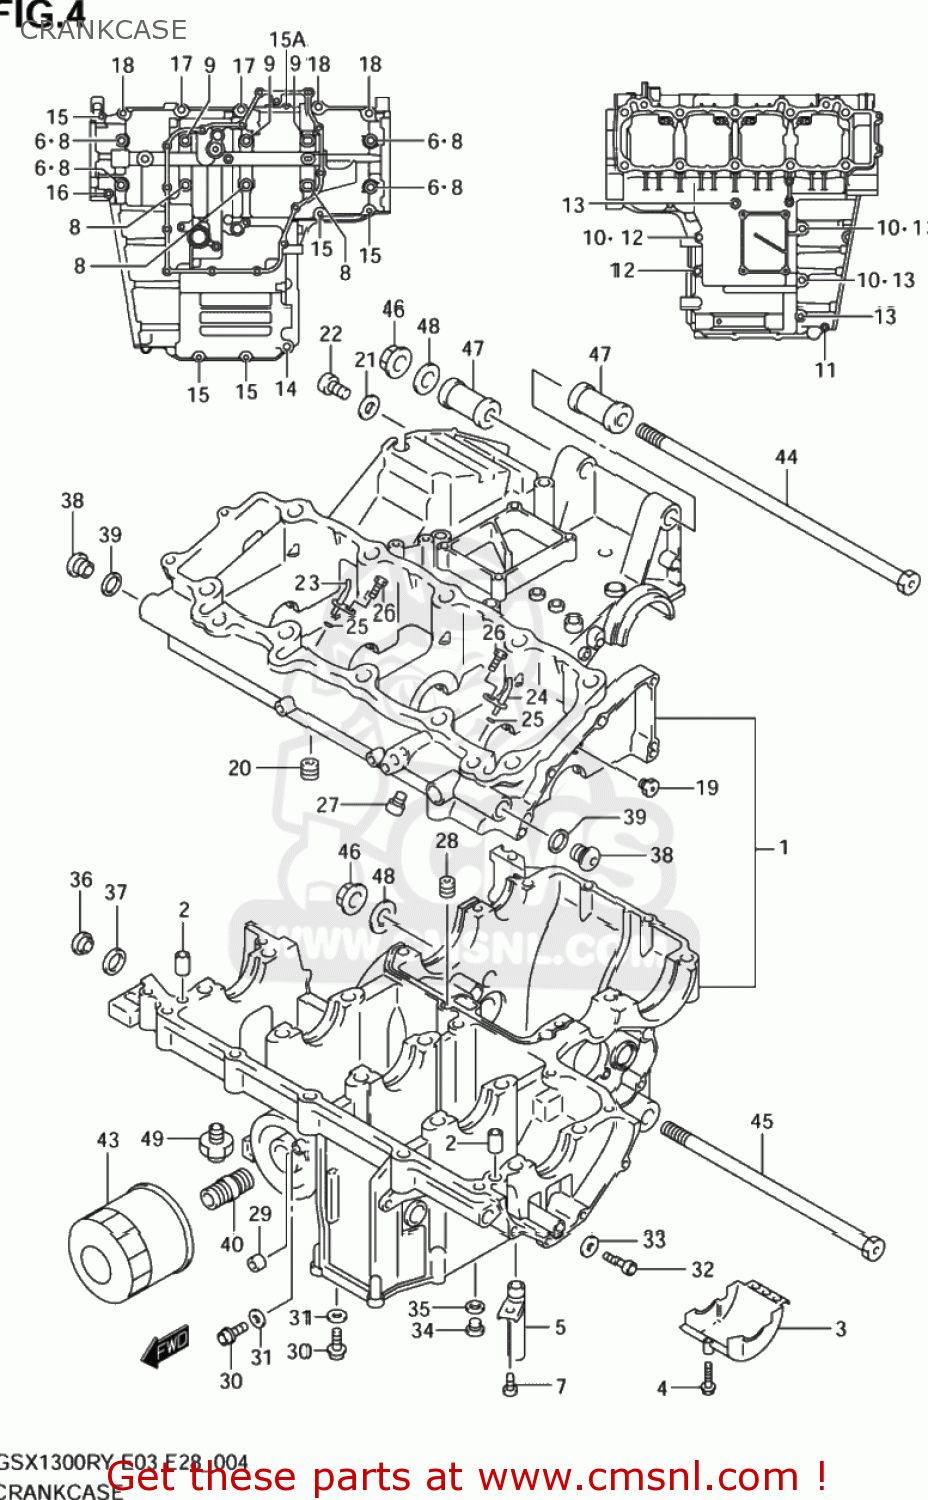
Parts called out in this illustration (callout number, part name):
1	CRANKCASE SET
2	PIN,CRANKCASE
3	SEPARATOR,OIL
4	SCREW
5	UNION,BREATHER
6	GASKET(10.2X20X2).3 (NAS)
7	BOLT
8	BOLT(9X95)
9	BOLT(9X115)
10	GASKET(8.2X14X1) (NAS)
11	BOLT
12	BOLT
13	BOLT (8X80)
14	BOLT
15	BOLT
15A	BOLT
16	BOLT
17	BOLT
18	BOLT
19	JET,MAGNETO COOLING
20	JET,AIR(100)
21	GASKET(5.8X13X1.2) (NAS)
22	BOLT
23	JET,PISTON COOLINGR
24	JET,PISTON COOLING
25	O RING(D:1.2,ID:4)
26	BOLT(6X12)
27	BOLT(6X10)
28	JET,AIR(180)
29	JET,OIL PAN GALLERY
30	BOLT
31	GASKET(5.8X13X1.2) (NAS)
32	BOLT
33	GASKET(8.2X14X1) (NAS)
34	PLUG(10X10)
35	GASKET(10X14X3.6) (NAS)
36	PLUG,16X8
37	GASKET(16X22X2) (NAS)
38	PLUG,14X12
39	GASKET(13.8X18.8X4.8) (NAS)
40	UNION,OIL STAND
41	BEARING,CRANK THRUST,L
42	BEARING,CRANK THRUST,L
43	FILTER ASSEMBLY,ENGINE OIL
44	BOLT 12X295
45	BOLT(12X240)
46	NUT
47	SPACER,ENG MTG(L47)
48	WASHER
49	SWITCH ASSY,OIL PRESSURE
